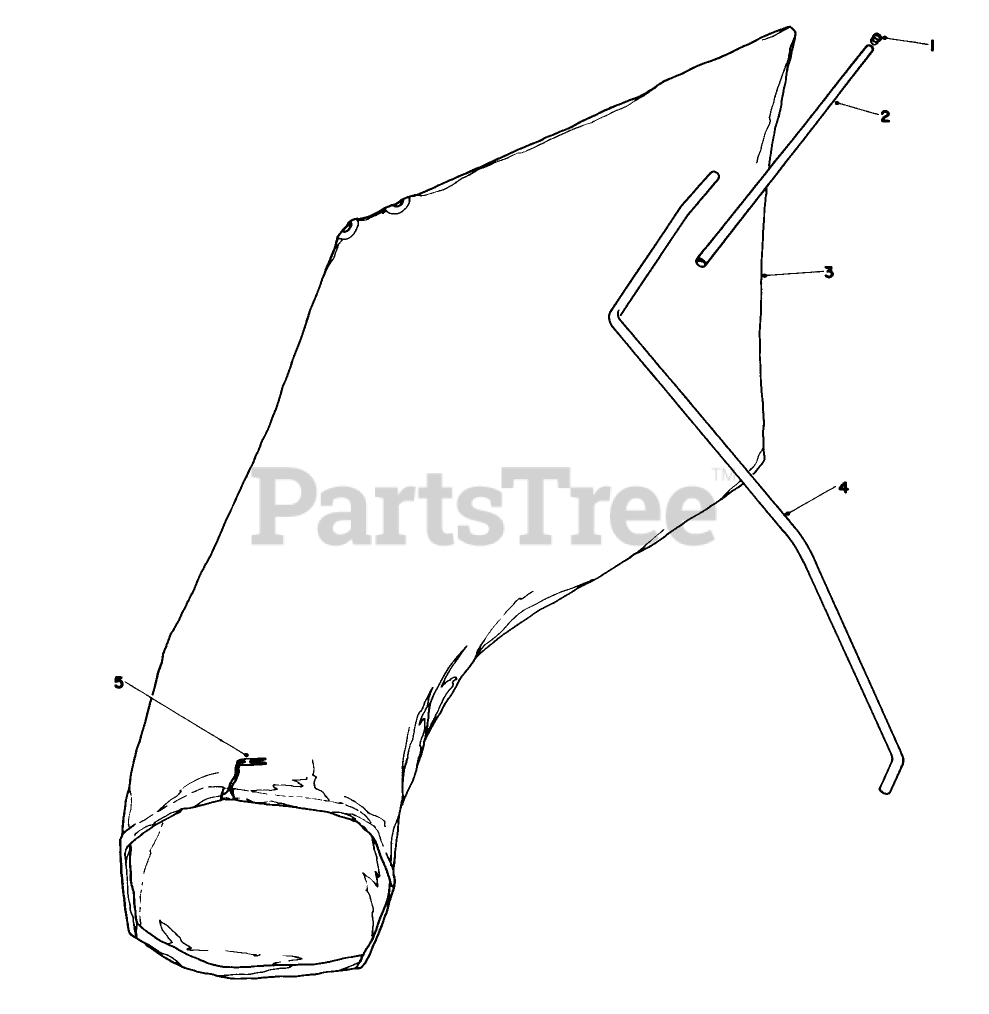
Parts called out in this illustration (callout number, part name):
2	BAG HANGER TUBE
3	Bag (Incl. Ref. #5)
4	HANGER ROD
5	BAG CORD FASTENER
